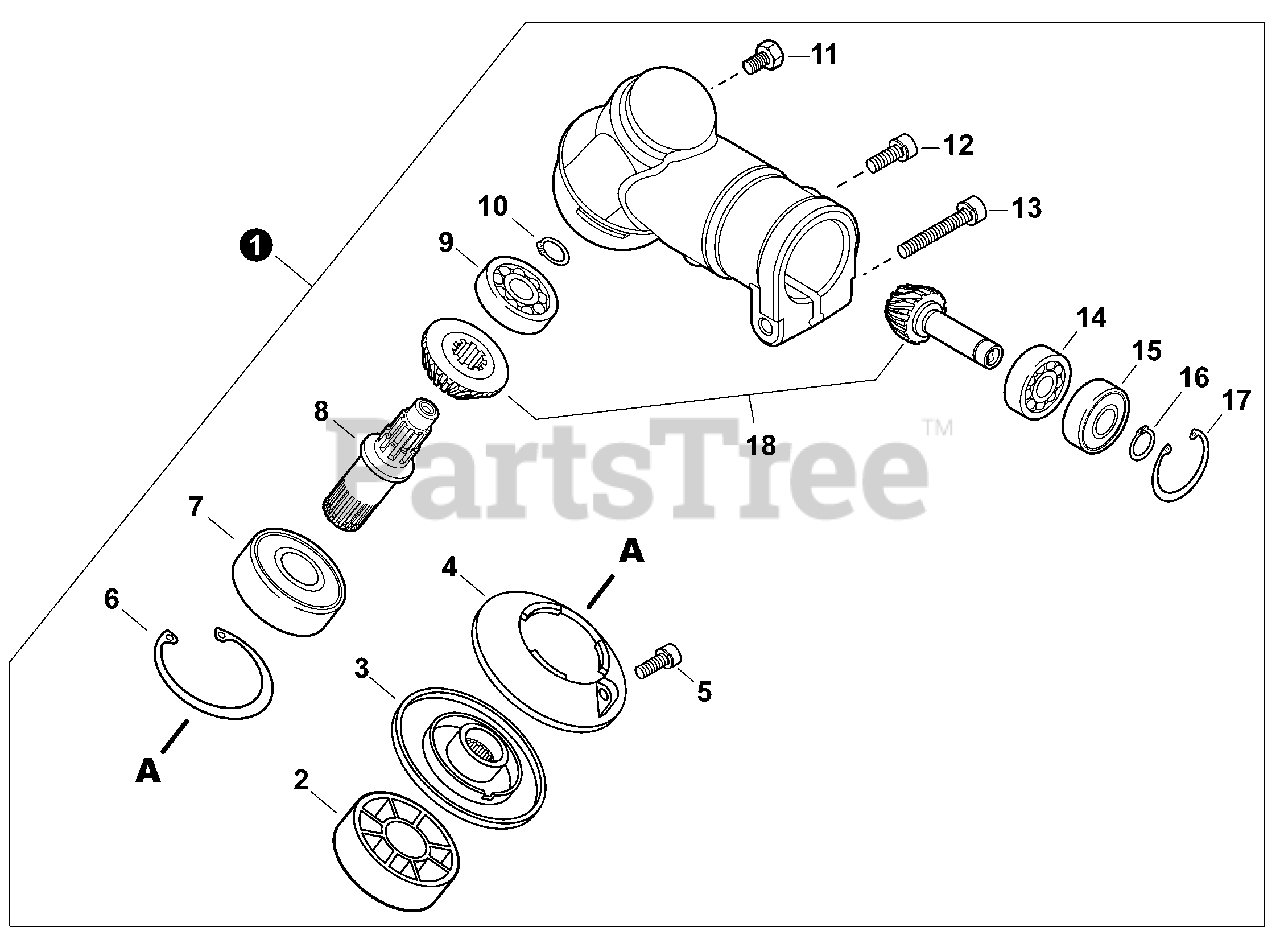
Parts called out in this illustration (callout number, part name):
1	GEAR CASE ASSY
2	SPACER, BLACK
3	PLATE, ADAPTOR - UPPER
4	COVER, GEAR CASE
5	BOLT 5×12
6	RING, SNAP 26
7	BEARING, BALL 6000DDU
8	SHAFT, GEAR
9	BEARING, BALL 626
10	RING, SNAP Ø6
11	BOLT M8×8
12	SCREW 5×12
13	BOLT M5×35
14	BEARING, BALL 609
15	BEARING, BALL 609
16	RING, SNAP Ø9
17	RING, SNAP 24
18	GEAR SET
